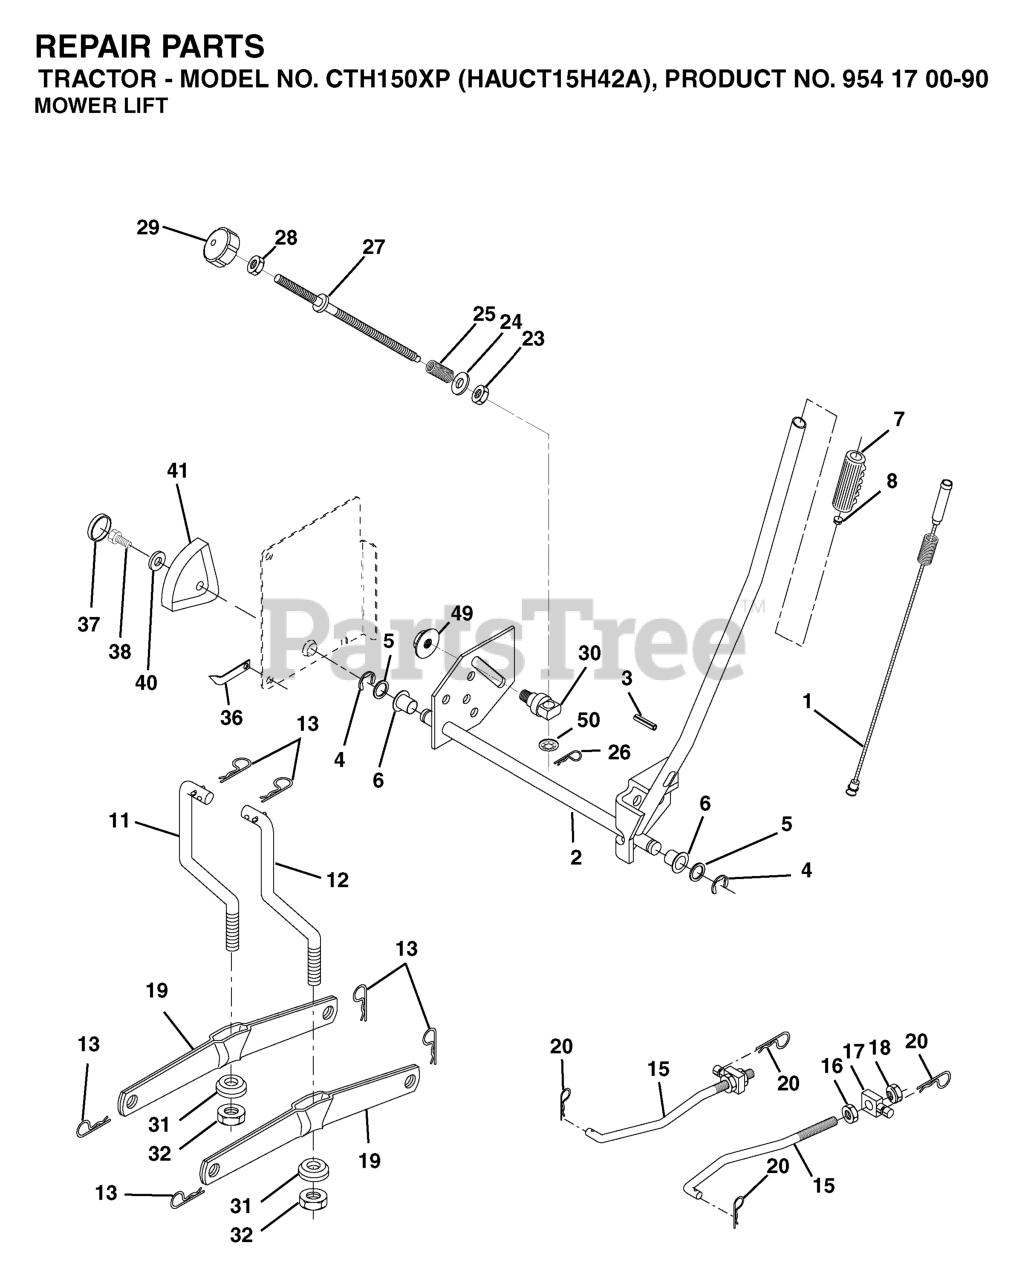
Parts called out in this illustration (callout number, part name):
1	WIRE ASM INNER W/ PLUNGER LT
2	SHAFT ASM R HANDLE
3	PIN GROOVE.
4	RETAINING RING LT
6	BEARING.NYLON
7	GRIP HANDLE
8	PLUNGER BUT KIT
11	LINK
12	LINK
13	RETAINER-SPRNG RB
15	LINK.SUSPENSION.FRONT
16	NUT.HEX.JAM.1/2-13
18	NUT.LK.W/WSH.1/2.
19	ARM.REAR.SUSPENSION
20	SPRING RETAINER
25	SPRING**
26	RETAINER CLIP
27	ROD ADJ LIFT
28	NUT
29	KNOB INF 3/8-16
31	BEARING.PIVOT.LIFT
32	NUT CROWNLOCK 3/8-24
36	POINTER, HEIGHT INDICATOR(2 2)
38	SCREW 5/16-18X1
41	HEIGHT INDICATOR
49	NUT
50	NUT PUSH M
